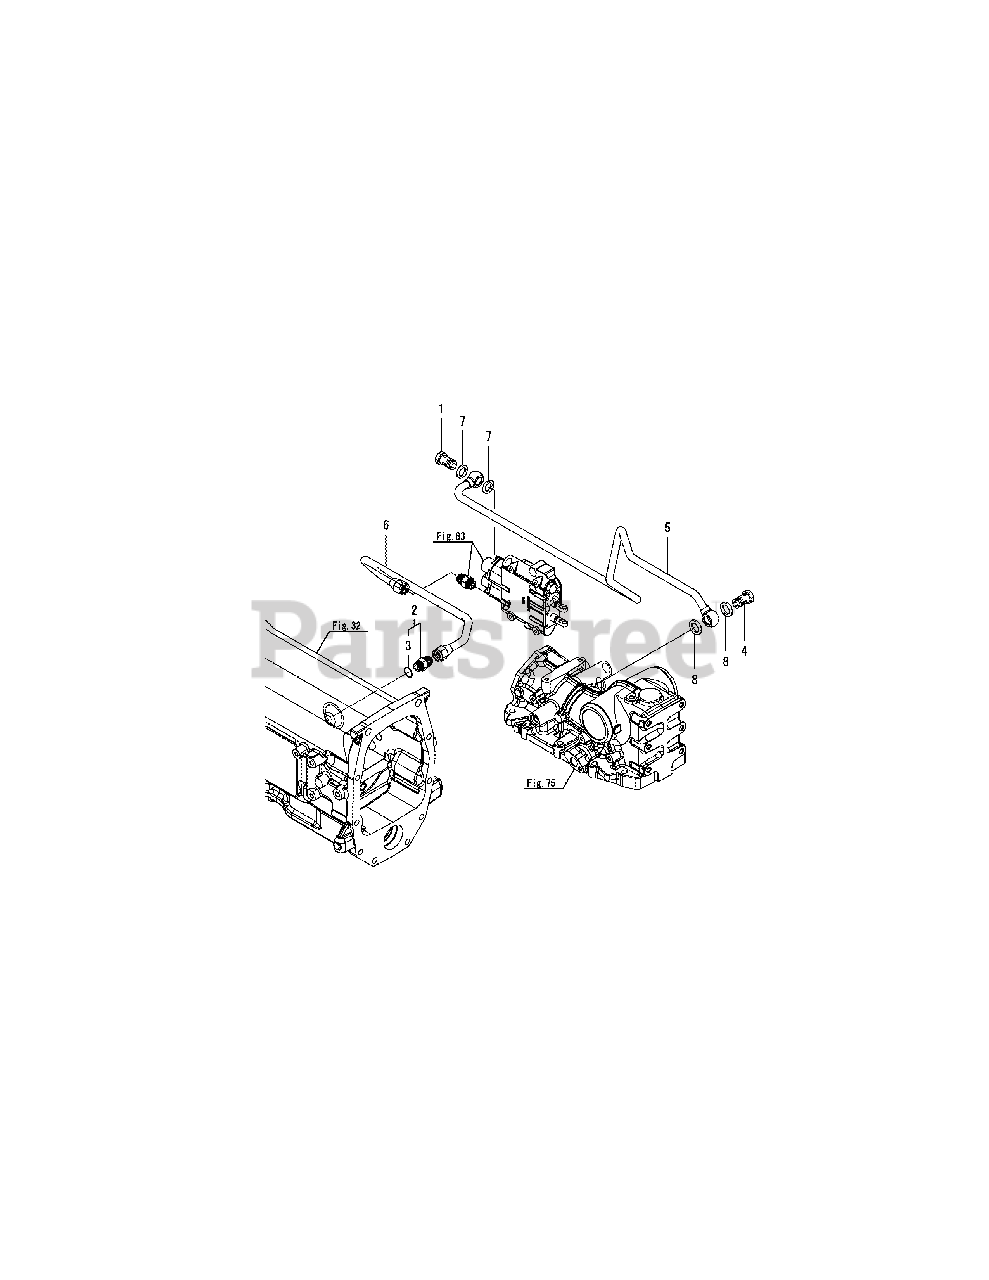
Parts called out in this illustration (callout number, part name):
2	FITTING/HYD, 3/4-7/8
5	HP PIPE, SCV-P
6	HP PIPE, SCV-T
